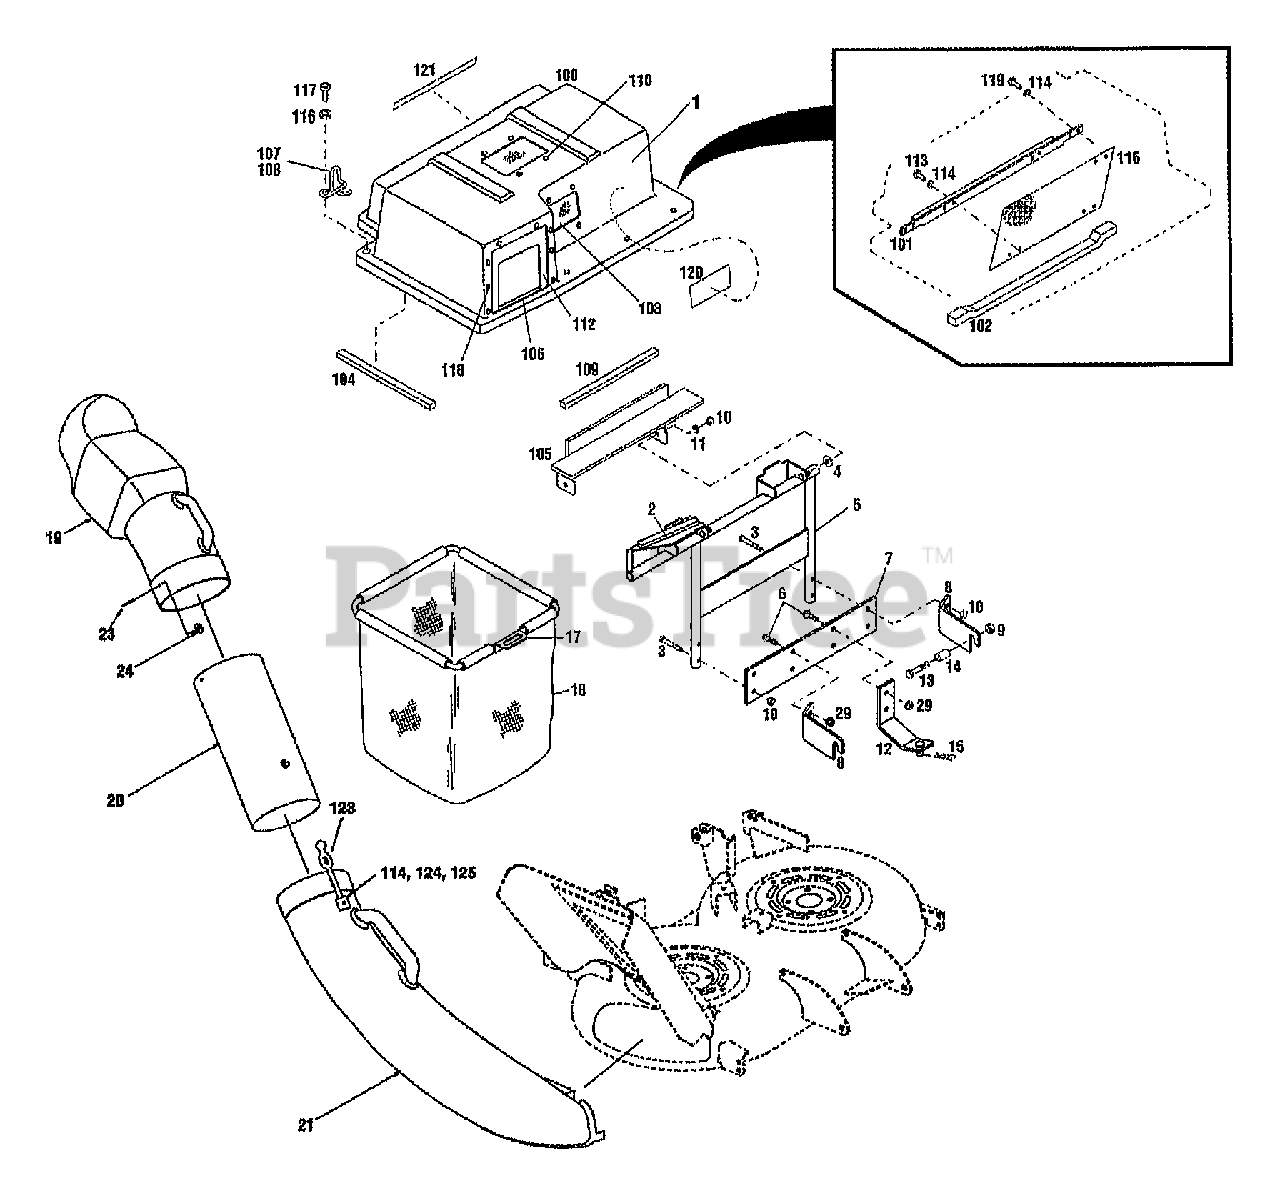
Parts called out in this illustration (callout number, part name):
1	ASSM-CVR GRASS BAG
2	SEAL-COVER 9.5"
3	SCR-HH 5/16-18X2.00
4	WASHER-.87X.34X.06 NYLON
6	SCR-HFLK 5/16-18X1.00 ZP
7	PLATE-SUPPORT
8	PLATE-SIDE MOUNTING
9	NUT-TOP LOCK 1/2-13 ZP
10	NUT-TOP/LK 5/16-18 ZP
11	WASHER-FLAT 5/16 SAE
12	SUPPORT-MOUNTING
13	SCR-HH 1/2-13X1.5 G5 ZP
14	SPACER-ATTACHMENT
15	PIN-HITCH .125X2.56 ZP
17	ASSM-FRAME GRASSBAG
18	ASSM-GRASS BAG
19	CHUTE-UPPER BAGGER
20	ASSM-GRASS GUIDE
21	ASSM-LWR BAGGER CHUTE
23	RIVET-POP 3/16"DIA
24	WASHER-.505X.22X.05
100	ASSM-CVR GRASS BAG
101	BRKT-ANGLE
102	COVER-SEAL
103	WINDOW
104	SEAL-COVER
105	ASSM-HINGE SUPPORT
106	CHUTE REINFORCEMENT
107	COVER-LOCK RH
108	COVER-LOCK LH
109	SEAL-COVER
110	RIVET-POP
112	GASKET-CHUTE
113	RIVET-POP 3/16 X 5/8
114	WASHER-.505X.22X.05
116	WASHER-.88X.2X.059
117	RIVET-POP 3/16X1/2
118	RIVET-POP .125
119	RIVET-POP
120	DECAL-INST
121	DECAL-LOGO
123	LATCH-RUBBER
125	POP-RIVET
